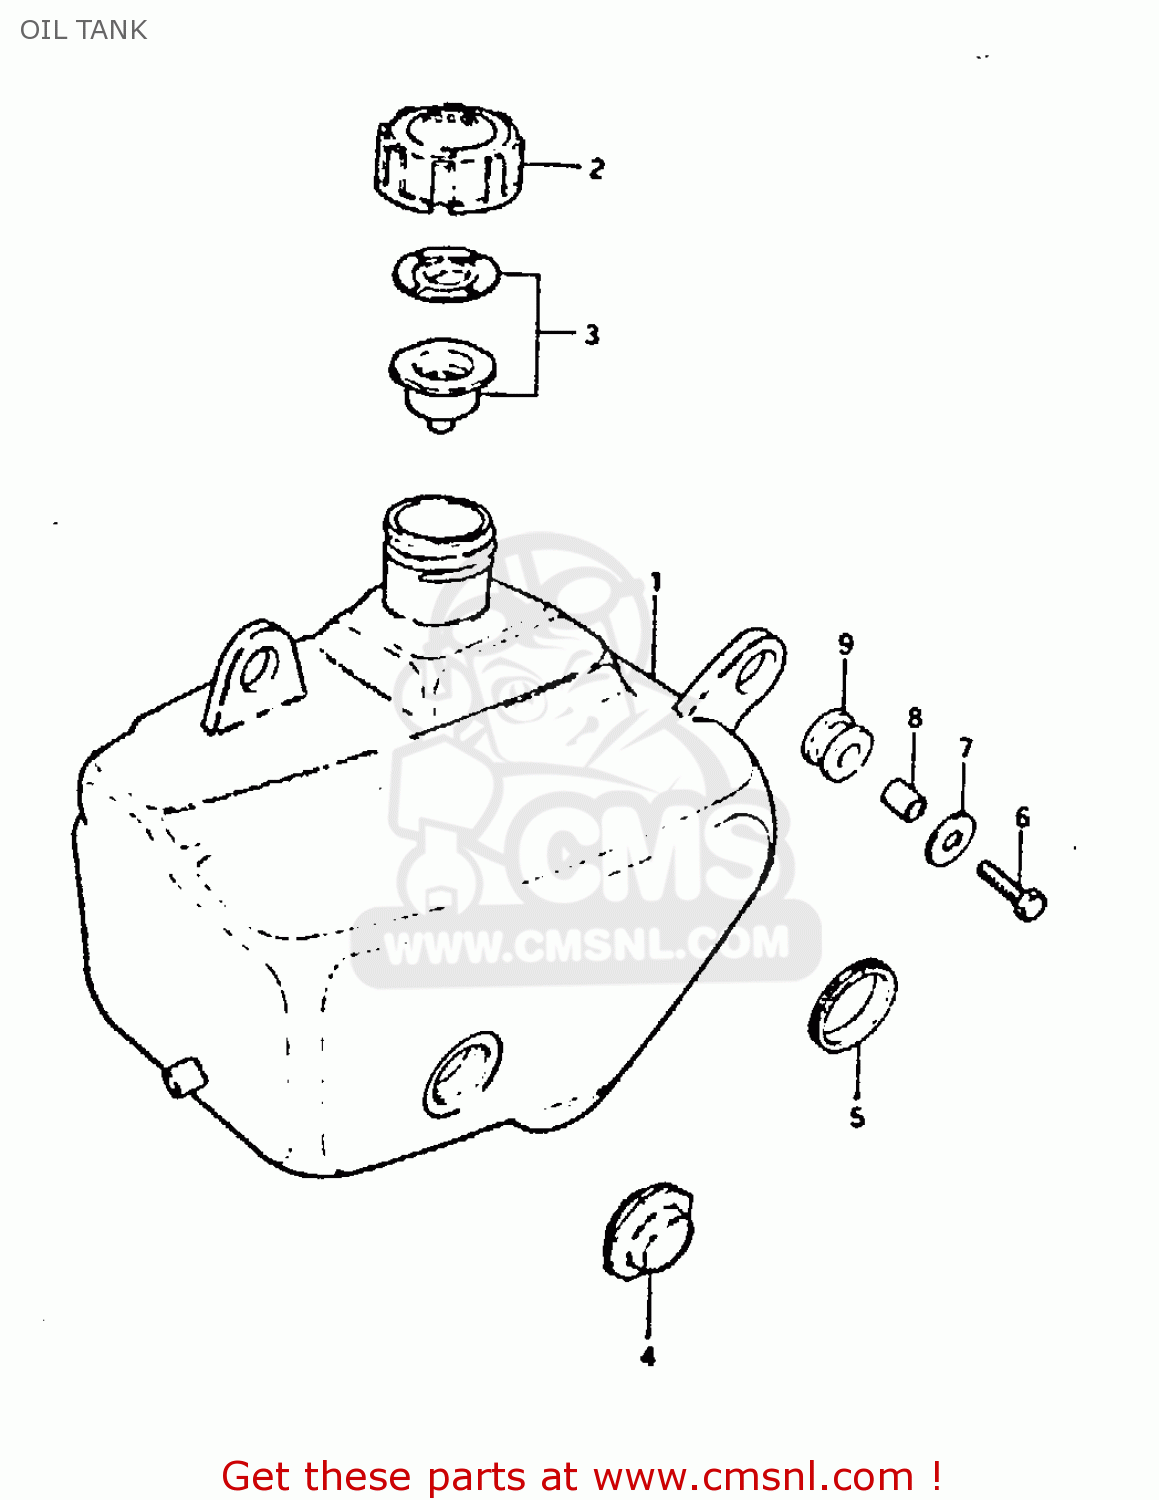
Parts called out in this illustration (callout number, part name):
1	TANK, OIL
2	CAP,OIL TANK
3	GASKET SET (NAS)
4	LENS SET,OIL LEVEL
5	RUBBER
6	BOLT
7	WASHER
8	SPACER (6.8X10X10)
9	CUSHION
